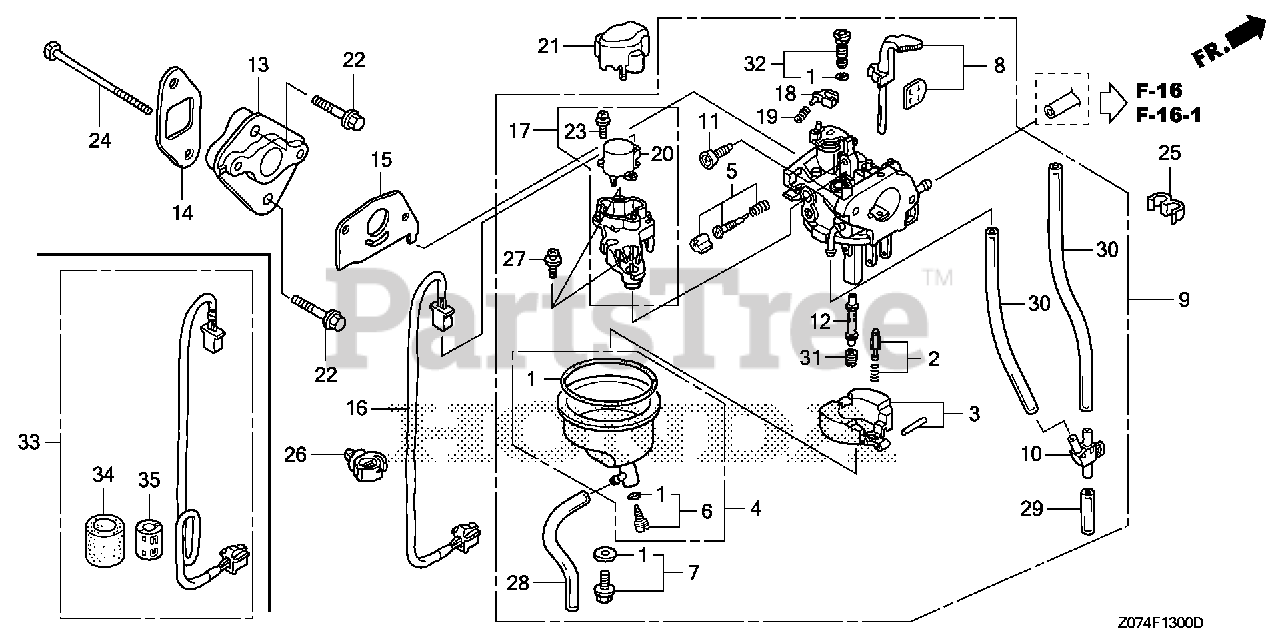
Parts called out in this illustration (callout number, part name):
1	GASKET SET
2	VALVE SET, FLOAT (SEAT NOT INCLUDED)
4	CHAMBER SET, FLOAT
5	SCREW SET, PILOT
6	SCREW SET, DRAIN
7	SCREW SET
9	CARBURETOR ASSY. (BF30E B)
9	CARBURETOR ASSY. (BF30E D/E)
10	JOINT, AIR VENT TUBE
11	SCREW, THROTTLE STOP
12	NOZZLE, MAIN
13	INSULATOR, CARBURETOR
14	GASKET, INSULATOR
15	GASKET, CARBURETOR
16	SUB-WIRE ASSY.
17	MOTOR ASSY., THROTTLE CONTROL
18	LEVER, LINK
19	SPRING, COMPRESSION COIL
20	MOTOR, THROTTLE CONTROL
21	COVER, THROTTLE MOTOR
22	BOLT, FLANGE (6X25) (NSHF)
23	SCREW-WASHER (3X8)
24	BOLT, HEX. (5X95)
25	CLAMP, TUBE (7X8)
26	CLIP, WIRE HARNESS (25MM)
27	SCREW-WASHER (4X10)
28	BULK HOSE, VINYL (3.5X6.5X8000) (3.5X6.5X240)
29	BULK HOSE, VINYL (4X7X8000) (4X7X30)
30	BULK HOSE, VINYL (4X7X8000) (4X7X230)
31	JET, MAIN (#58)
31	JET, MAIN (#60)
31	JET, MAIN (#62)
32	JET SET, PILOT (#35)
